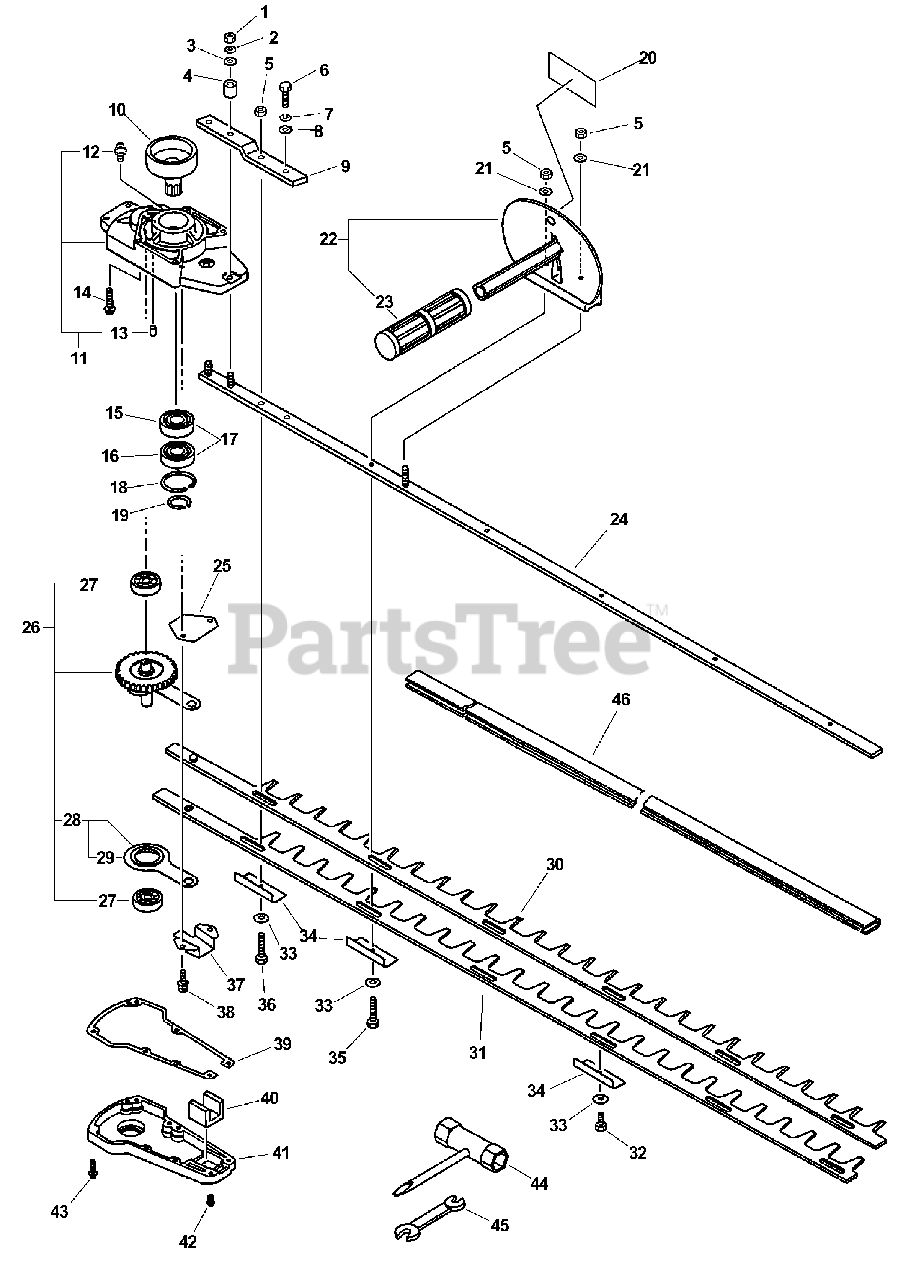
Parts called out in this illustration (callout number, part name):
1	LOCKNUT - 6
2	LOCKWASHER - 6
3	WASHER - 6
5	LOCKNUT - 6
6	BOLT - 6X10
7	LOCKWASHER - 6
8	WASHER - 6
9	BRACKET, ANGLE
10	DRUM, CLUTCH
11	CASE, GEAR
12	FITTING, GREASE
13	PIN - LOCATING
14	SCREW - 5X30
15	BEARING, BALL - 6904
16	BEARING, BALL - 6904
17	BEARING, BALL - 6003
18	RING, RETAINING - 37
18	RING, RETAINING - 35
19	RING, RETAINING - 19
19	RING, RETAINING - 16
20	LABEL - CAUTION
21	WASHER - 6
22	HANDLE ASSY - FRONT
23	GRIP, HANDLE
24	SUPPORT, BLADE
25	PLATE, GUIDE
26	GEAR ASSY
27	BEARING, BALL - 6200
28	CONNECTING ROD ASSY
29	BEARING, NEEDLE
30	BLADE - UPPER
31	BLADE - LOWER
34	INSULATOR
36	BOLT - 6
37	GUIDE
37	GUIDE, BLADE
38	SCREW - 5X14
39	GASKET, GEAR CASE
40	SEAL, FELT
41	LID, GEAR CASE
42	SCREW - 4X14
43	SCREW - 4X22
44	T-WRENCH - 13X19mm
45	SPANNER - 8X10mm
46	COVER, BLADE
